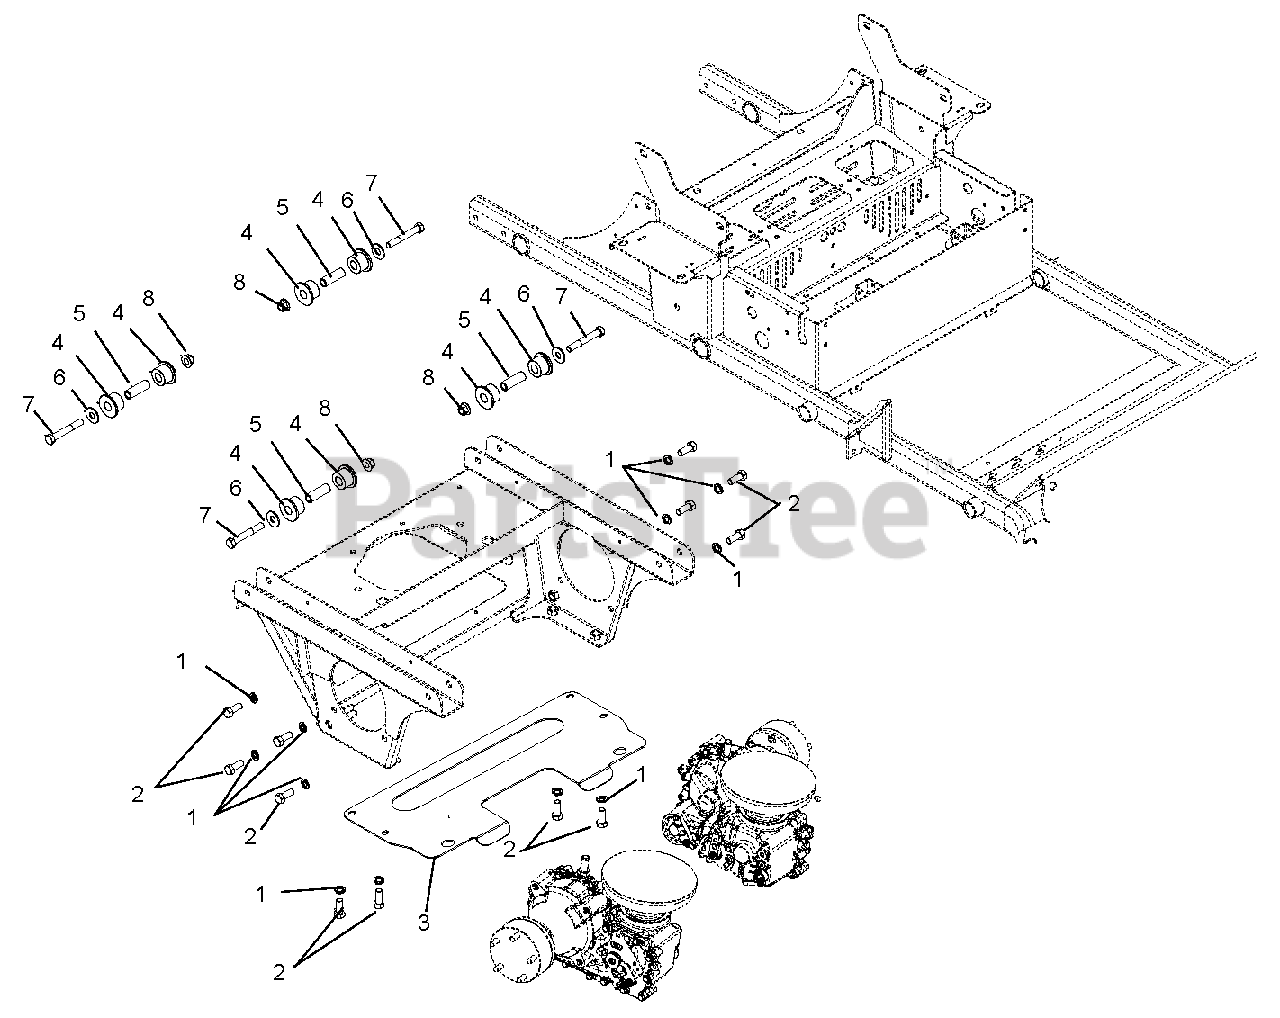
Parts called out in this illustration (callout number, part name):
1	Washer, Lock .50 x .125 REG YWZC
2	Bolt, Hex .50-13 x 1.25 Grade 5 YWZC
3	Plate, Transmission Connecting
4	Bushing, Flange .75 x 1.51 x 1.13 x 2.0 URE
5	Bushing, Sleave .50 x .75 x 2.23
6	Washer, Flat Steel .563 x 1.38 x .109 YWZC
7	Bolt, Hex .50-13 x 3.50 Grade 5 YWZC
8	Nut, Locking Nyloc Flange .50-13 YWZC
